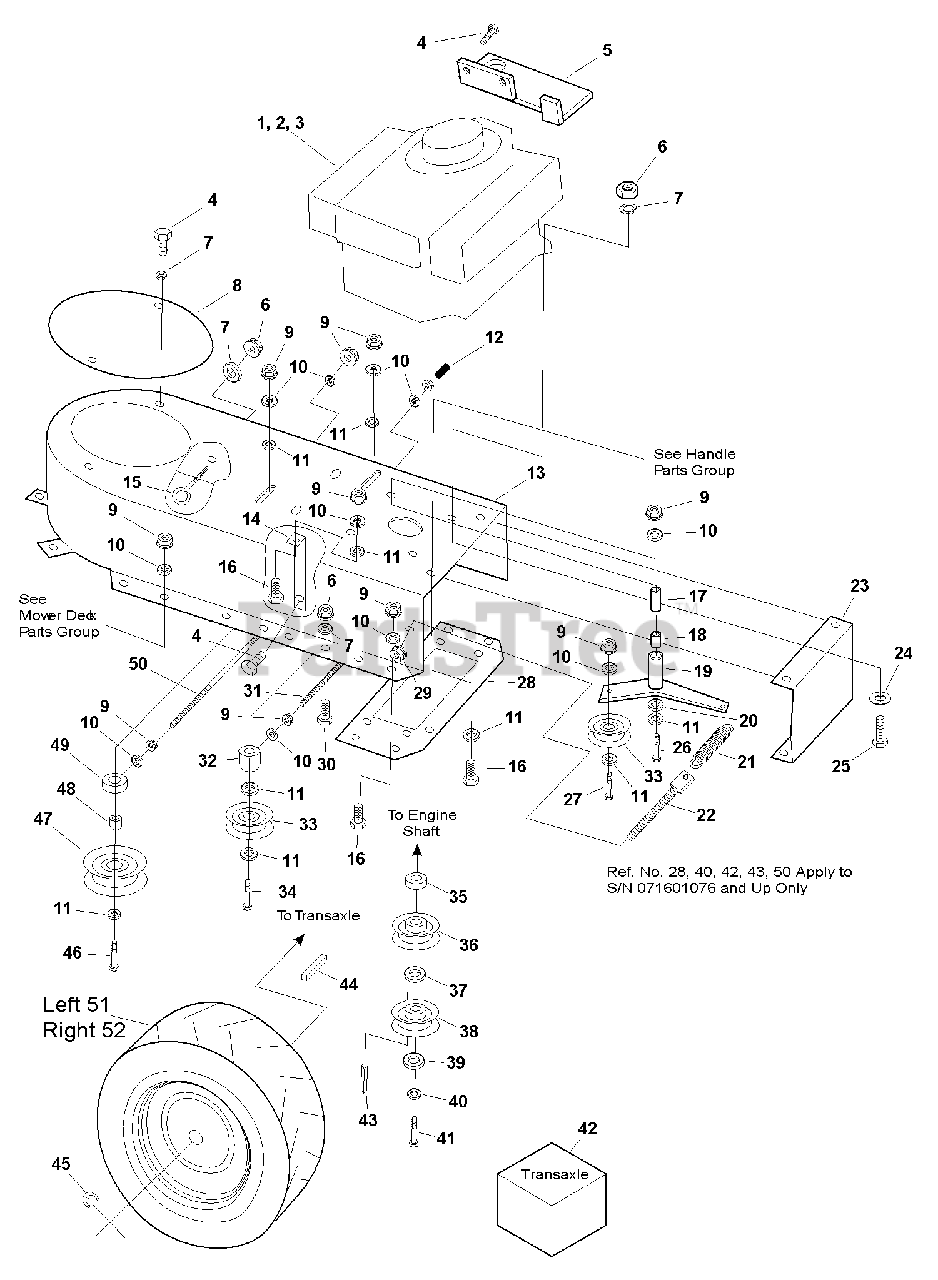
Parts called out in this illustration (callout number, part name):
1	Engine - 13.5 HP Briggs & Stratton
2	Engine - 13 HP Honda
3	Engine - 15 HP Kawasaki
4	Capscrew, Hex Head, 5/16-18 x 3/4
5	Auxiliary fuel tank base
6	Nut, Hex, 5/16-18
7	Lockwasher, 5/16
8	Clutch Cover Plate
9	Nut, Hex, 3/8-16
10	Lockwasher, 3/8
11	Flatwasher, 3/8
13	Engine deck (S/N 071601075 & Below)
13	Engine deck (S/N 071601076 & Up)
14	Transmission Forward Mounting Hanger
15	Eyebolt, 5/16-18x3-1/4
16	Capscrew, Hex Head, 3/8-16 x 1
17	Idler Arm Pivot Boss
18	Sleeve Bushing, 3/4 ID
19	Transmission Idler Arm
20	Flatwasher, 1/2
21	Idler Spring
22	Idler Tension Rod
23	Engine deck back cover
24	Washer, Plain, 5/16
25	Capscrew, 5/16-18 x 1-1/2
26	Capscrew, 3/8-16 x 3-1/4
27	CAPSCREW, Hex Head, 3/8-16 x 1-3/4
28	Lower handle mounting plate
29	3/8-16 Reverse Locknut
30	Capscrew, 5/16-18 x 2-1/4
31	Trans belt idler tensioning rod
32	Transmission Idler Boss
33	Idler Pulley
34	3/8-16 x 4 hex bolt
35	Engine Shaft Spacer, 1"
36	Blade Clutch Drive Pulley
37	Engine Shaft Spacer - 1/4"
38	Transmission Drive Pulley
39	Flatwasher Heavy Duty, 7/16
40	Lockwasher, 7/16
41	Capscrew, Socket Head, 7/16-20 x 1-1/2
43	Key, Engine Shaft, 1/4 x 1/4 x 2-1/8
44	Key, Axle Shaft 3/16 x 3/16 x 1-3/8
46	Capscrew, Hex Head, 3/8-16 x 3-1/4
47	Blade clutch idler pulley
48	Idler pulley spacer bushing
49	Blade Clutch Idler Boss
50	Blade Clutch Idler Tensioning Rod
51	Drive Wheek, Left
